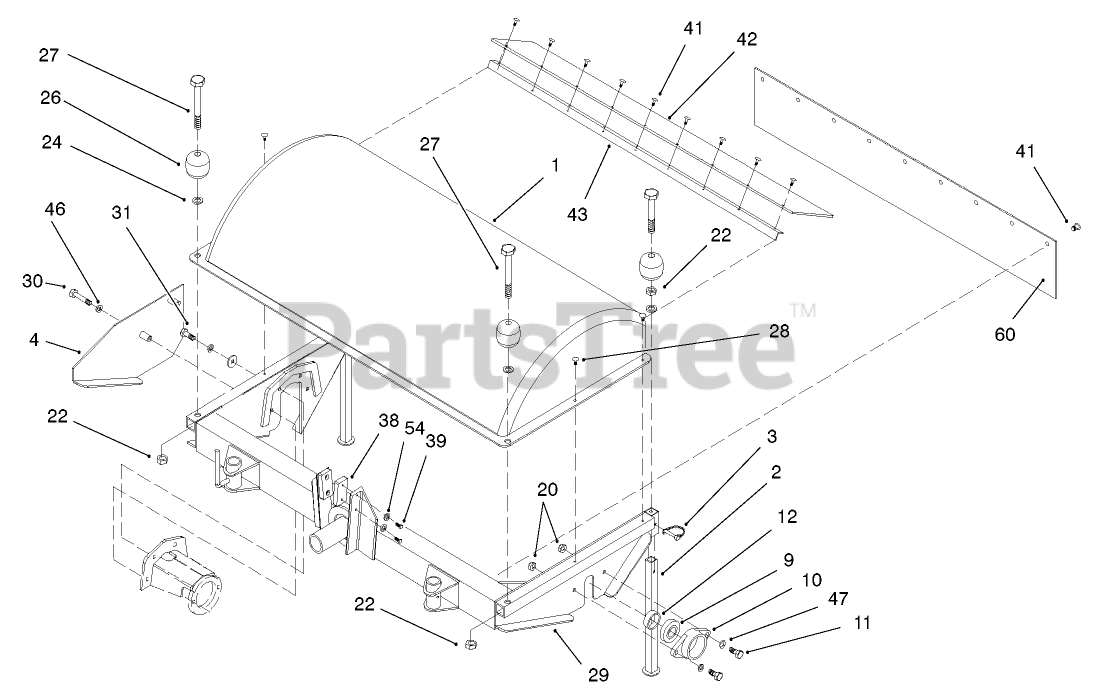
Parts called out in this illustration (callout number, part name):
1	COVER-BROOM
2	STAND-HEAD, BROOM
3	PIN-LYNCH
4	PLATE-GUARD, MOTOR
9	BEARING
10	HOUSING-BEARING
11	SCREW-HH
12	COLLAR-LOCKING
20	NUT-HEX
22	NUT-JAM
24	WASHER
26	ROLLER
27	SCREW-HH
28	SCREW
29	BROOM HEAD FRAME ASM
30	SCREW-HH
31	SCREW-HH
38	BUMPER-RUBBER
39	SCREW-HH
41	RIVET-POP
42	BELTING-RUBBER
43	PLATE-MOUNT, GUARD
46	WASHER-LOCK
47	WASHER-FLAT
54	WASHER-LOCK
60	FLAP-REAR
